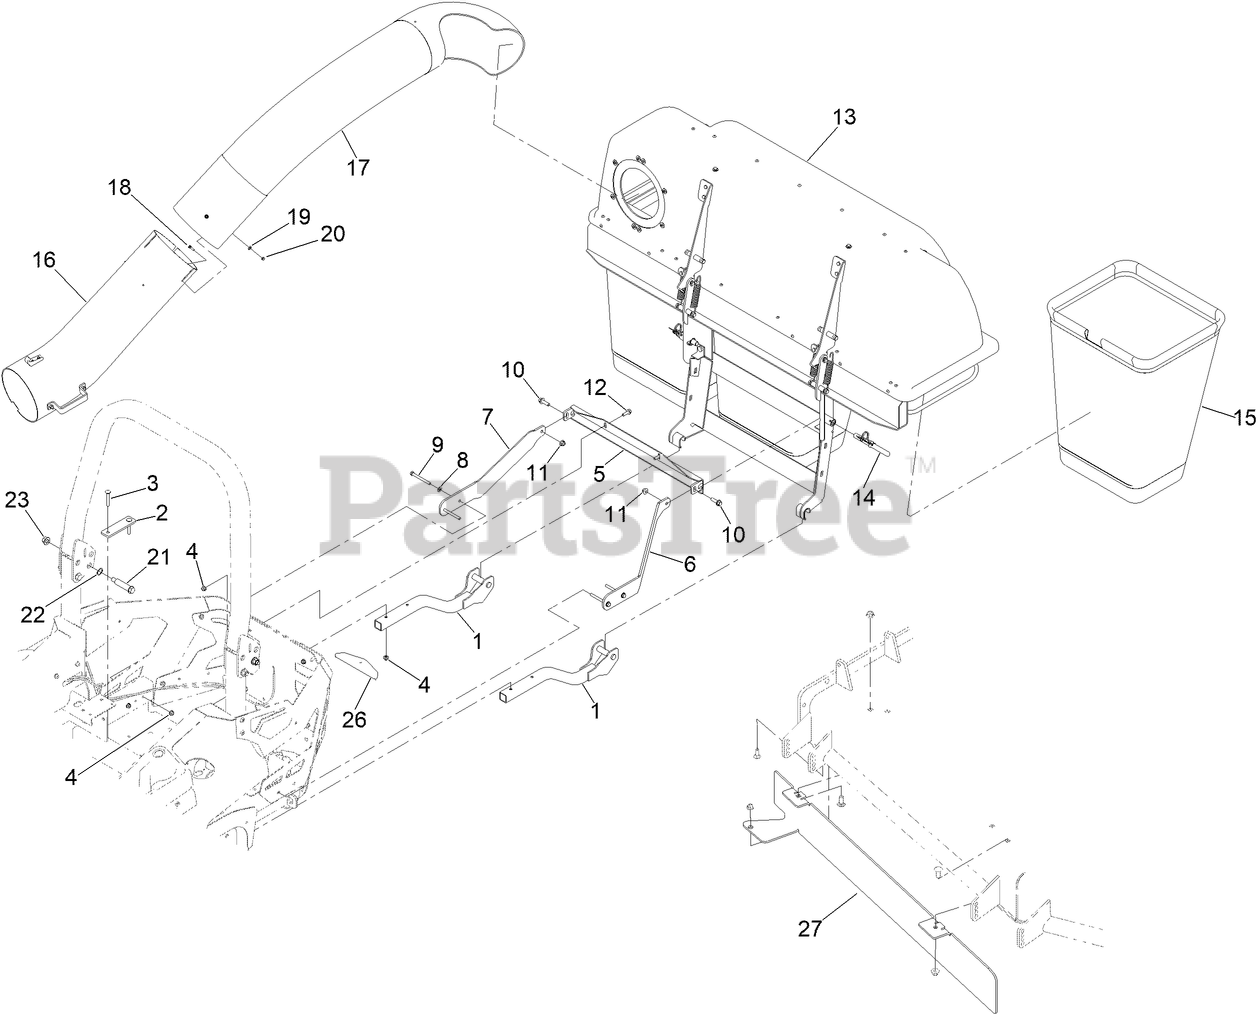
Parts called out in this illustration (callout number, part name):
1	SUPPORT, LOWER [BLACK]
2	PLATE-BACKER
3	BOLT-CARR
4	NUT-HF, NI
5	SUPPORT-BAGGER, UPPER
6	BRACKET-UPPER, LH
7	BRACKET-UPPER, RH
8	WASHER-PLAIN
9	SCREW-HH
10	SCREW-HHF
11	NUT-HF, NI
12	SCREW-HHF
13	TRIPLE BAG HOOD ASM
14	PIN-MOUNT, BAGGER
15	BAG AND FRAME ASM
16	LOWER TUBE ASM
17	TUBE-UPPER
18	SCREW-HWH
19	WASHER-FLAT
20	NUT-LOCK, NI
21	BOLT-SHOULDER
22	WASHER-WAVE
23	NUT-LOCK
26	COVER-HITCH
27	BAFFLE-BLOWER [RED]
